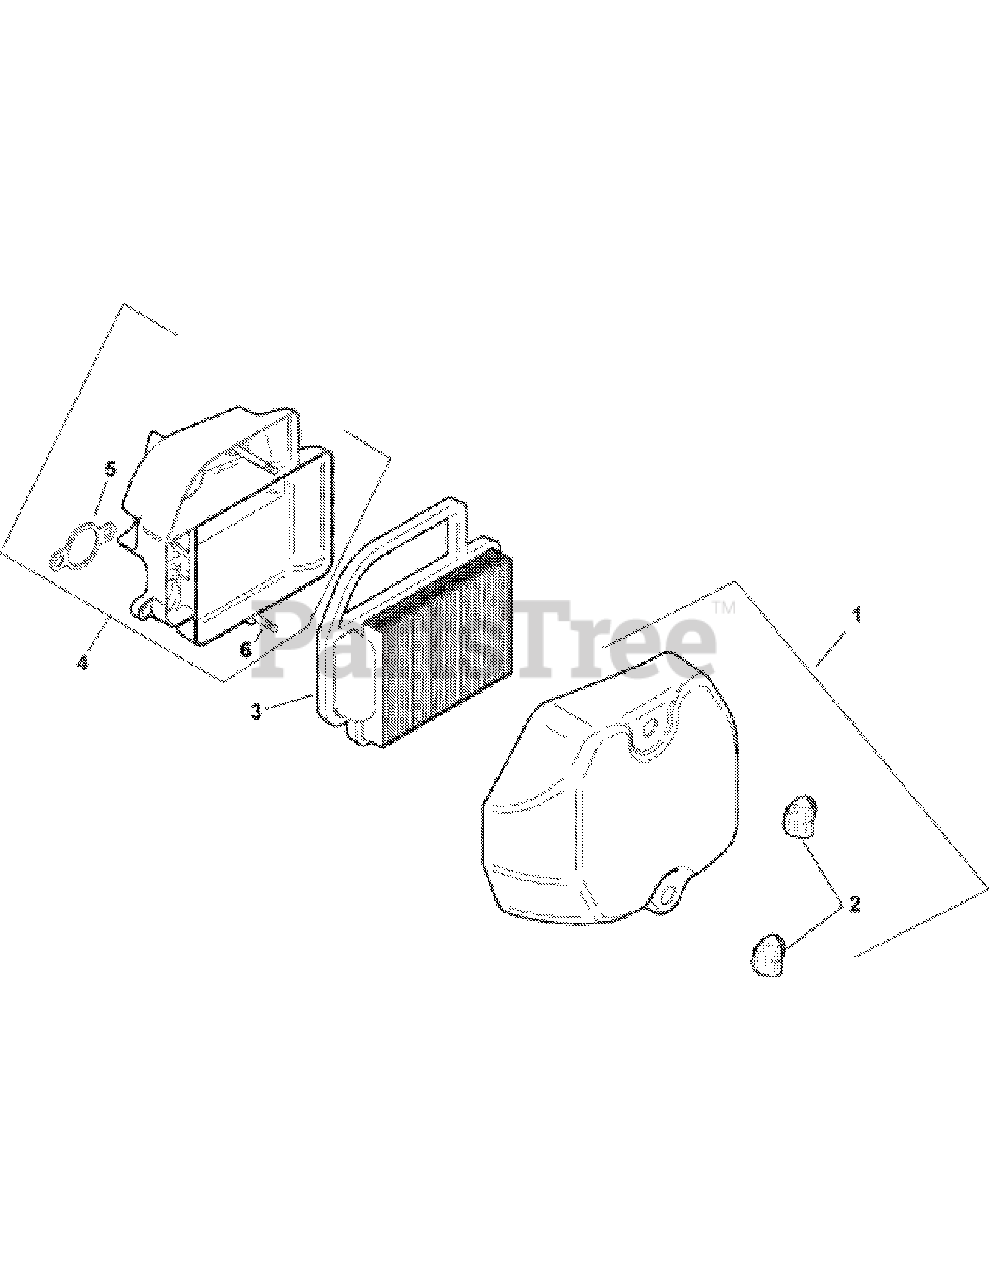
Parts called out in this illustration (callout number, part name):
1	KIT, AIR CLEANER COVER
3	ELEMENT, AIR CLEANER
4	KIT, AIR CLEANER BASE
5	GASKET, AIR CLEANER BASE
6	STUD, AIR CLEANER BASE
